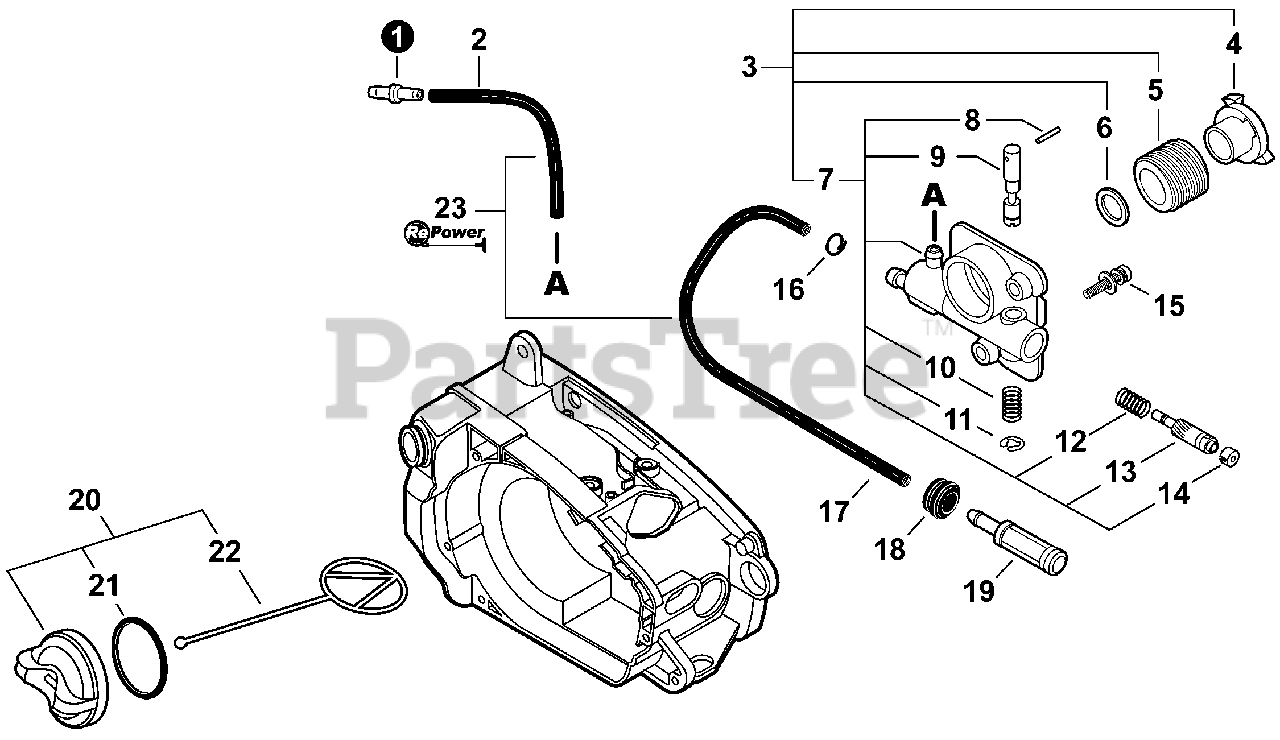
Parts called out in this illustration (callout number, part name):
1	CONNECTOR, PIPE
2	PIPE, 3×6×45 BLACK
3	AUTO-OILER ASSY
4	COLLAR 10
5	GEAR, WORM
6	WASHER 10.5×17.4×1.8
7	AUTO-OILER
8	PIN, SPRING
9	ADJUSTER, OILER
13	PLUNGER ASSY
14	CAP, OIL PUMP
15	SCREW 4×12
16	CLIP Ø6.5MM
17	PIPE, FUEL 3×6×150
18	GROMMET
19	FILTER, OIL
20	CAP ASSY, BLACK
21	O-RING 18
22	CONNECTOR, CAP L= 60mm
23	PIPE, BULK - REPOWER 3×6mm BLACK
